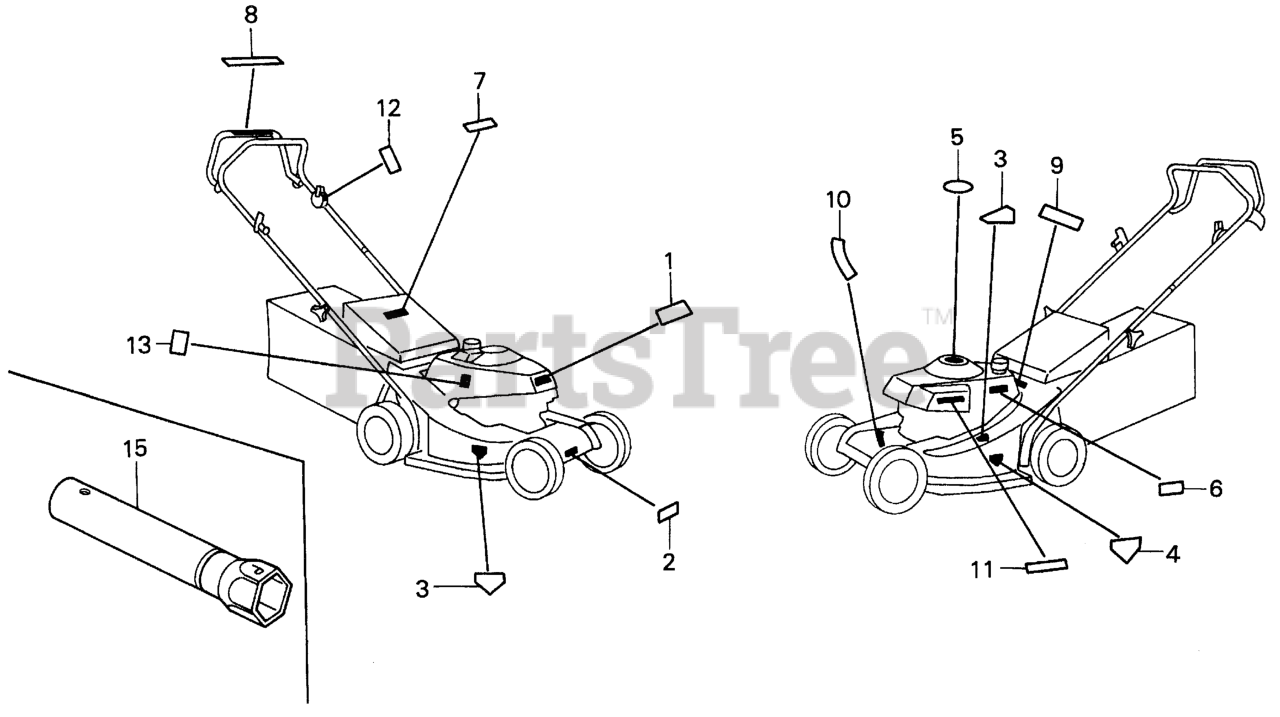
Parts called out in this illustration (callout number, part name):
2	CAUTION A, HOUSING (ENGLISH)
2	LABEL A, HOUSING CAUTION (ENGLISH)
2	MARK A, HOUSING DANGER (E)
3	LABEL C, HOUSING CAUTION
4	LABEL C, HOUSING CAUTION
5	CAUTION, OPERATOR (ENGLISH)
6	LABEL, FUEL CAUTION (ENGLISH)
7	LABEL, DISCHARGE GUARD CAUTION (ENGLISH) (NOT AVAILABLE)
8	MARK, BLADE CONTROL
9	PLATE, MANUFACTURE (NOT AVAILABLE)
9	PLATE, MANUFACTURE
10	LABEL, PLUG CAUTION (ENGLISH)
11	MARK, AIR CLEANER CAUTION (ENGLISH)
12	MARK, THROTTLE
13	MARK, OIL CAUTION
15	WRENCH, SPARK PLUG
